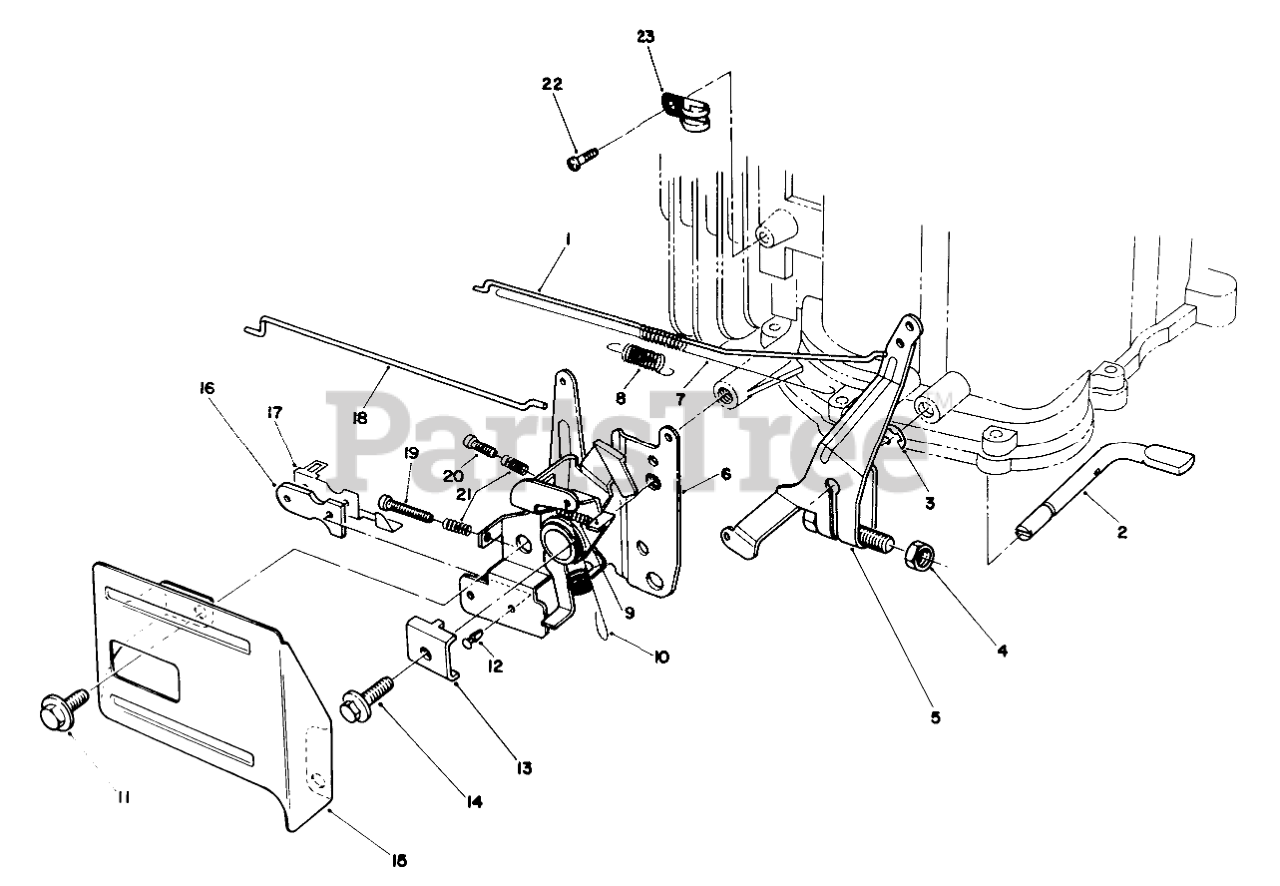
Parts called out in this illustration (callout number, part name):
1	Rod-Carburetor
2	SHAFT
3	E-RING
5	ARM ASM
6	THROTTLE
7	SPRING
8	SPRING
9	SPRING
10	SPRING
12	RIVET
13	CLAMP-CABLE
15	THROTTLE GUARD
16	INSULATOR-KILL SWITCH
17	TERMINAL-KILL SWITCH
18	Rod-Choke
19	SCREW
20	SCREW
21	SPRING
22	SCREW
23	Clamp
